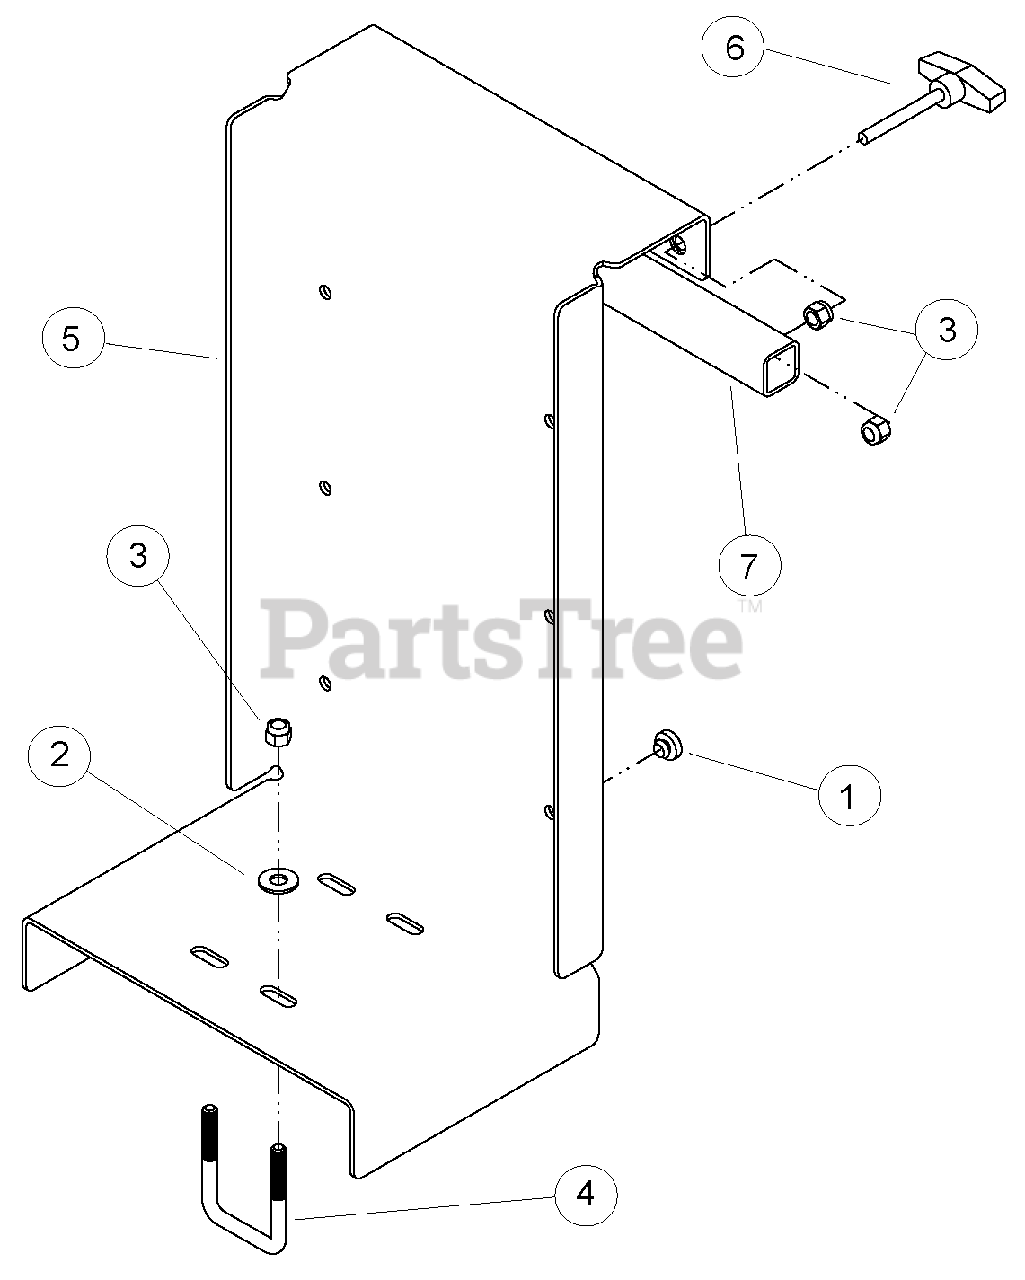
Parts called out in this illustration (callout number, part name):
1	GROMMET, RUBBER
2	WASHER, 3/8 FLAT
3	NUT, 3/8" NYLOCK
4	U-BOLT, 3/8-16 X 2.06 X 3.00 SQ ZP
5	WELDMENT, TAILGATE MOUNT
6	KNOB, 3/8 X 2-3/4 STUD
7	TUBE, 1-1/4 X 1-1/4 X 11-7/8
